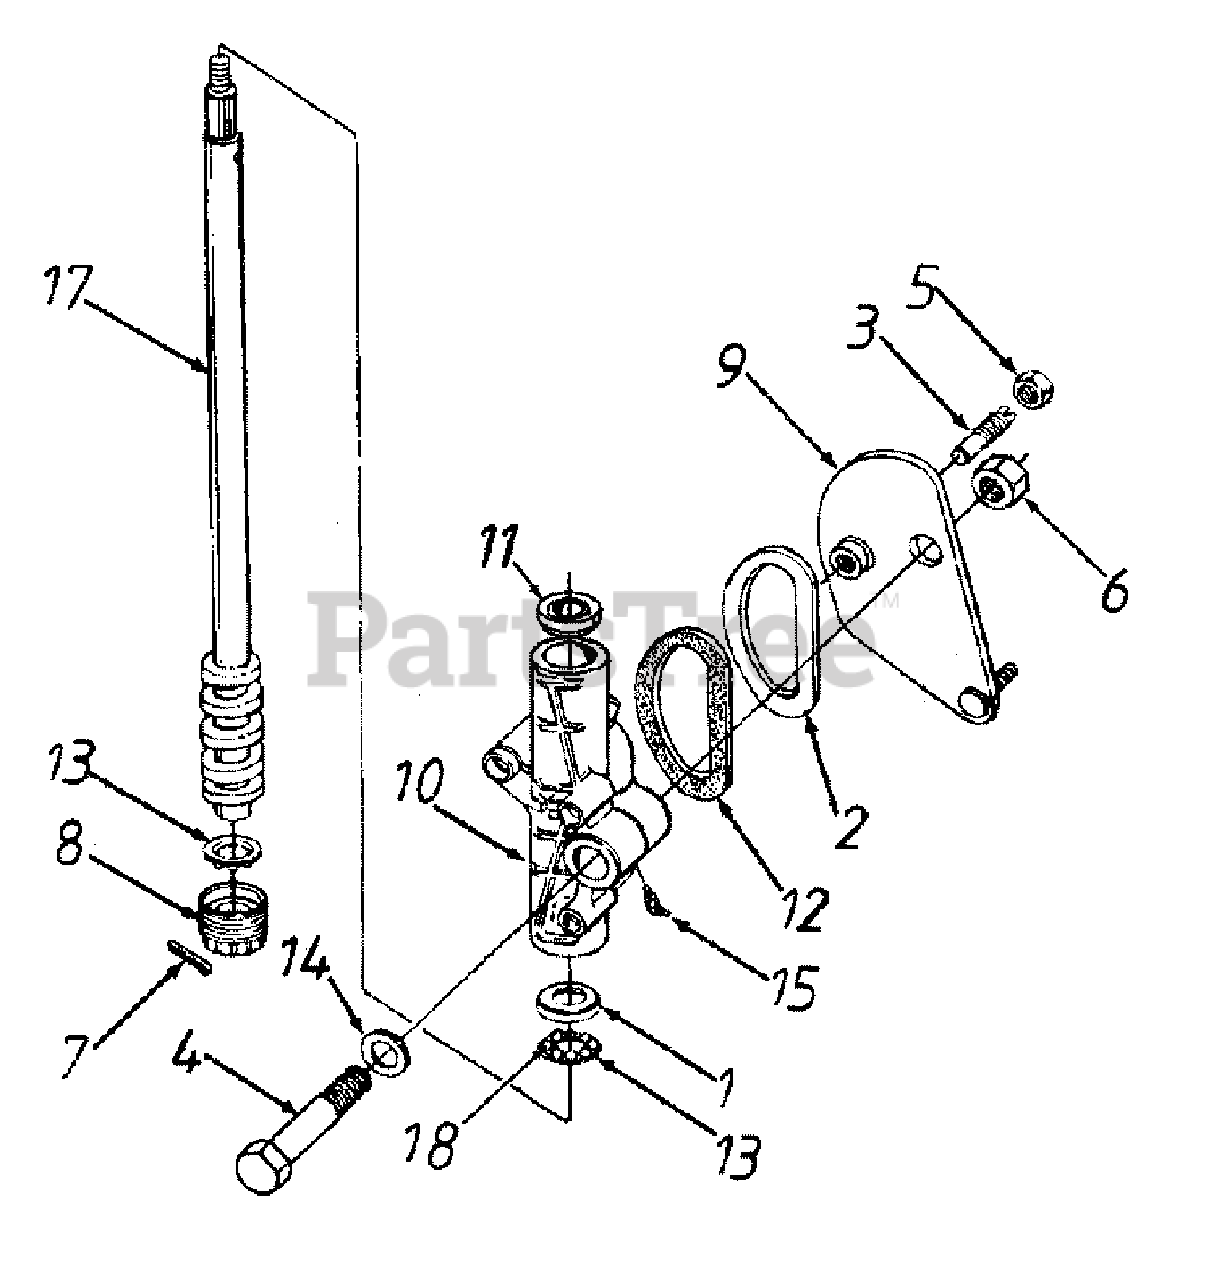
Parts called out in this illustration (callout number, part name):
1	Bearing Cup
2	Seal Retainer
3	Cam Follower
5	Hex Jam Nut 9/16-18 Thd.
6	Hex Crown L-Nut 5/8-18 Thd.
7	Cotter Pin 1/8" Dia.
8	Adjustment Plug Ass'y.
9	Steering Arm Ass'y.
10	Steering Hsg. Bushing Ass'y.
12	Seal
13	Ball Retainer
14	Fl-Wash. .781" I.D. x 1.25" O.D.
15	Grease Fitting
17	Steering Shaft Ass'y.
18	Ball Bearing
